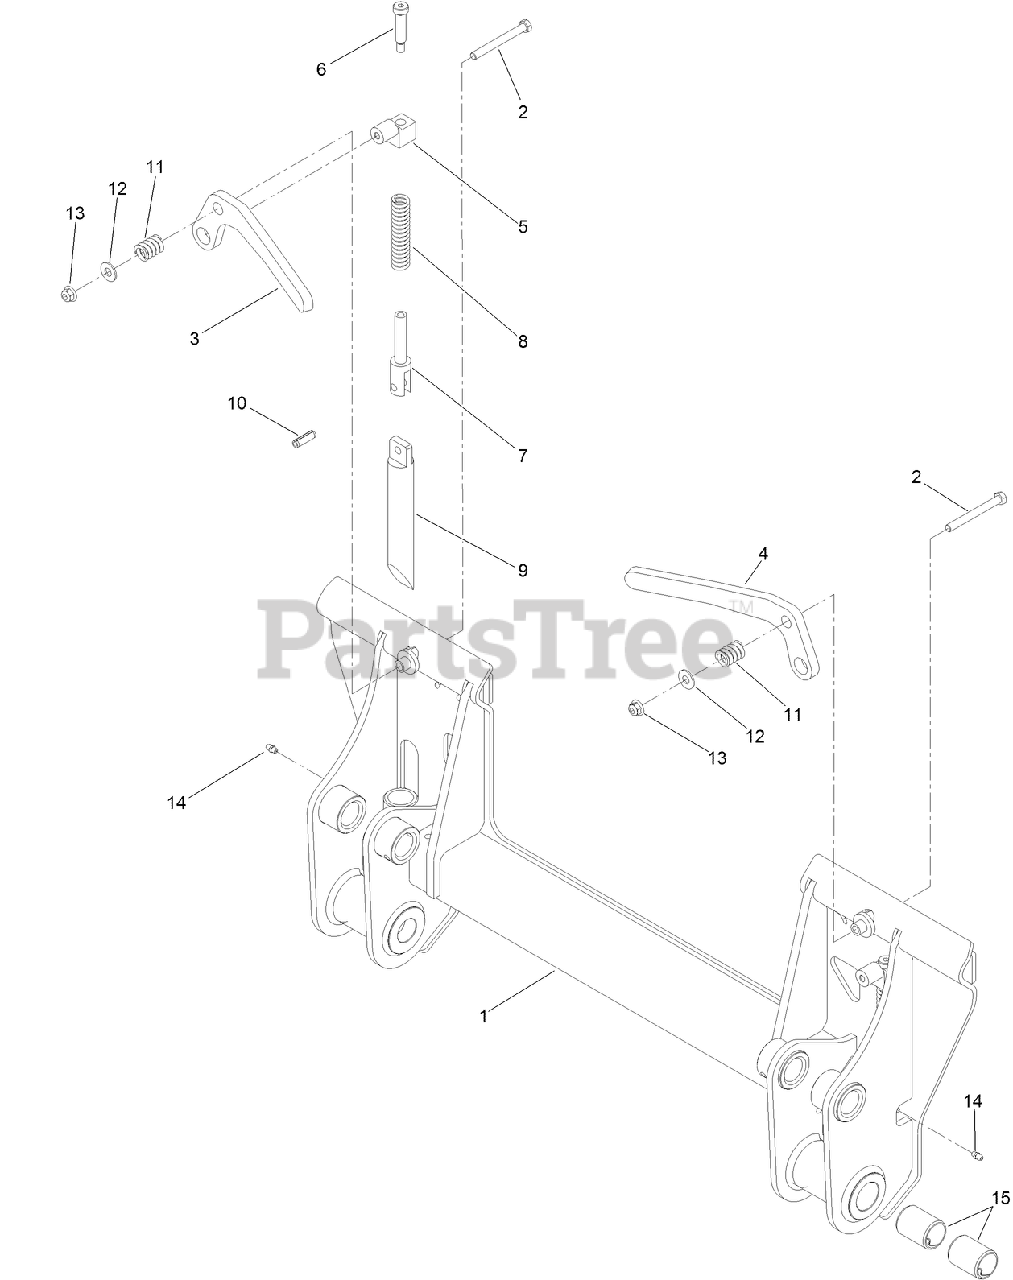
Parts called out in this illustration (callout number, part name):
1	MOUNT-QTACH
2	SCREW-HH
3	HANDLE-LEFT
4	HANDLE-RIGHT
5	BLOCK-STOP
7	LINK-HANDLE
8	SPRING-BRAKE
9	PIN-QTACH
10	PIN-ROLL
11	SPRING-COMPRESSION
12	WASHER-FLAT
13	NUT-HF, NI
14	FITTING-GREASE
15	BUSHING-SPRING
